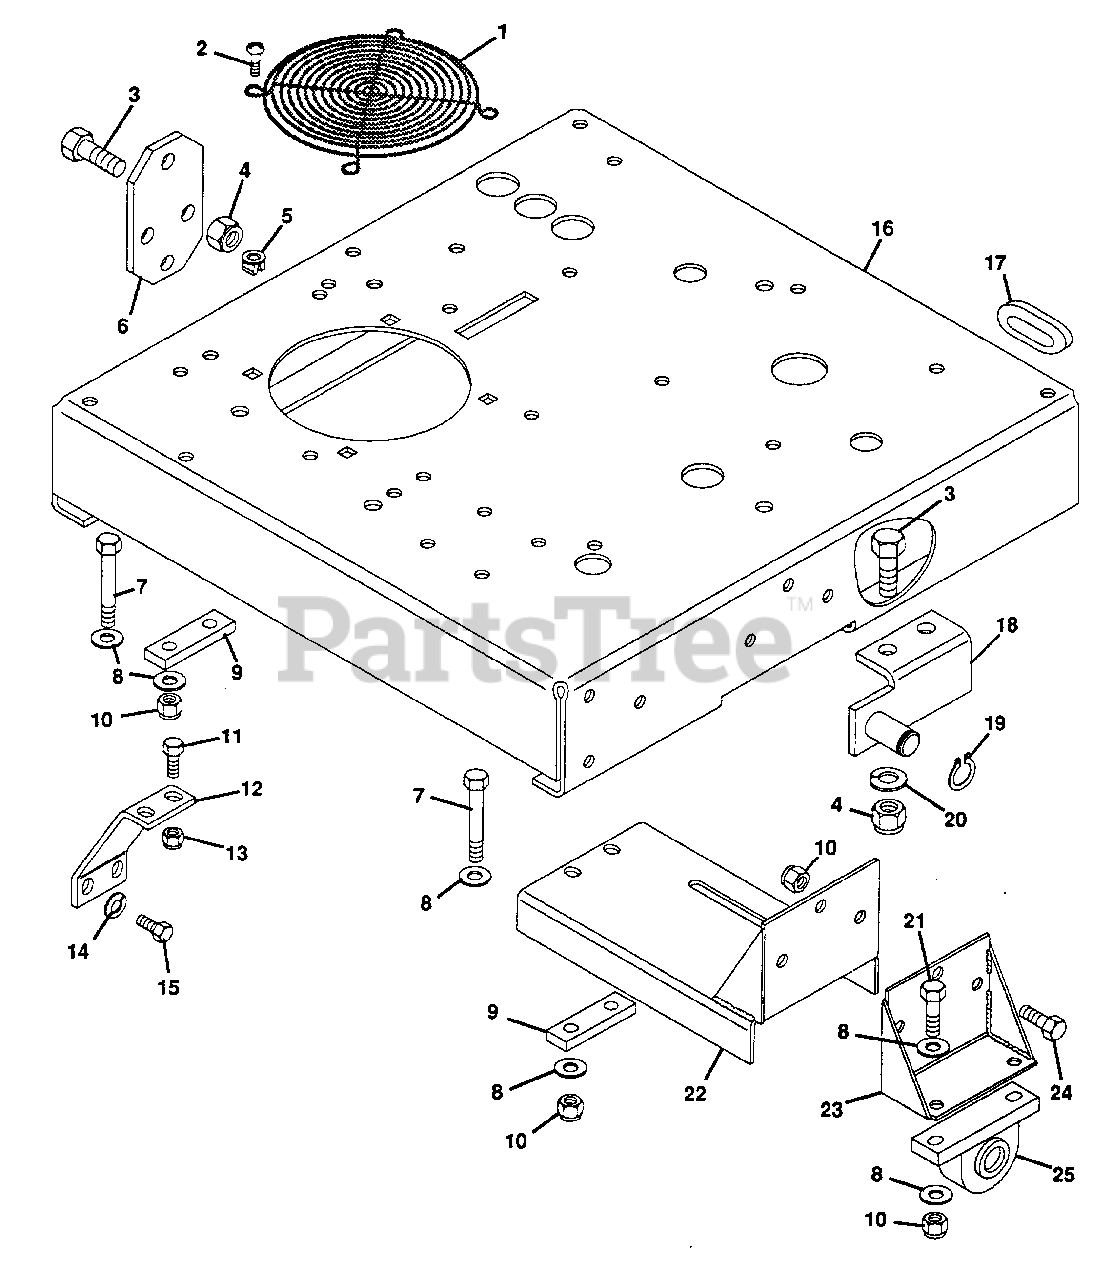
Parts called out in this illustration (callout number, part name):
1	GUARD, FAN
2	SCREW, 1/4-20X.50 SELF TAPPING
3	BOLT, HEX 1/2-13X1.50
4	NUT, LOCK 1/2-13
5	GROMMET, PLASTIC
6	PLATE
7	BOLT, HEX 3/8-16X3.25
8	WASHER, FLAT .406X.812X.065
9	SPACER
10	NUT, LOCK 3/8-16
11	BOLT, HEX 5/16-18X.875
12	BRACKET, TRANSAXLE SUPPORT
13	NUT, LOCK 5/16-18
14	WASHER, LOCK 5/16 REG.
15	BOLT, HEX 5/16-18X.75
16	FRAME, PRO MASTER 18-H
17	GROMMET
18	WELDMENT, PILOT L.H.
18	WELDMENT, PILOT R.H.
19	RING, RETAINING
20	WASHER, LOCK 1/2 REG.
21	BOLT, HEX 3/8-16X1.50
22	WELDMENT, AXLE SUPPORT BRACKET
23	WELDMENT, SUPPORT
24	BOLT, HEX 3/8-16X1.25
25	BEARING, PILLOW BLOCK
